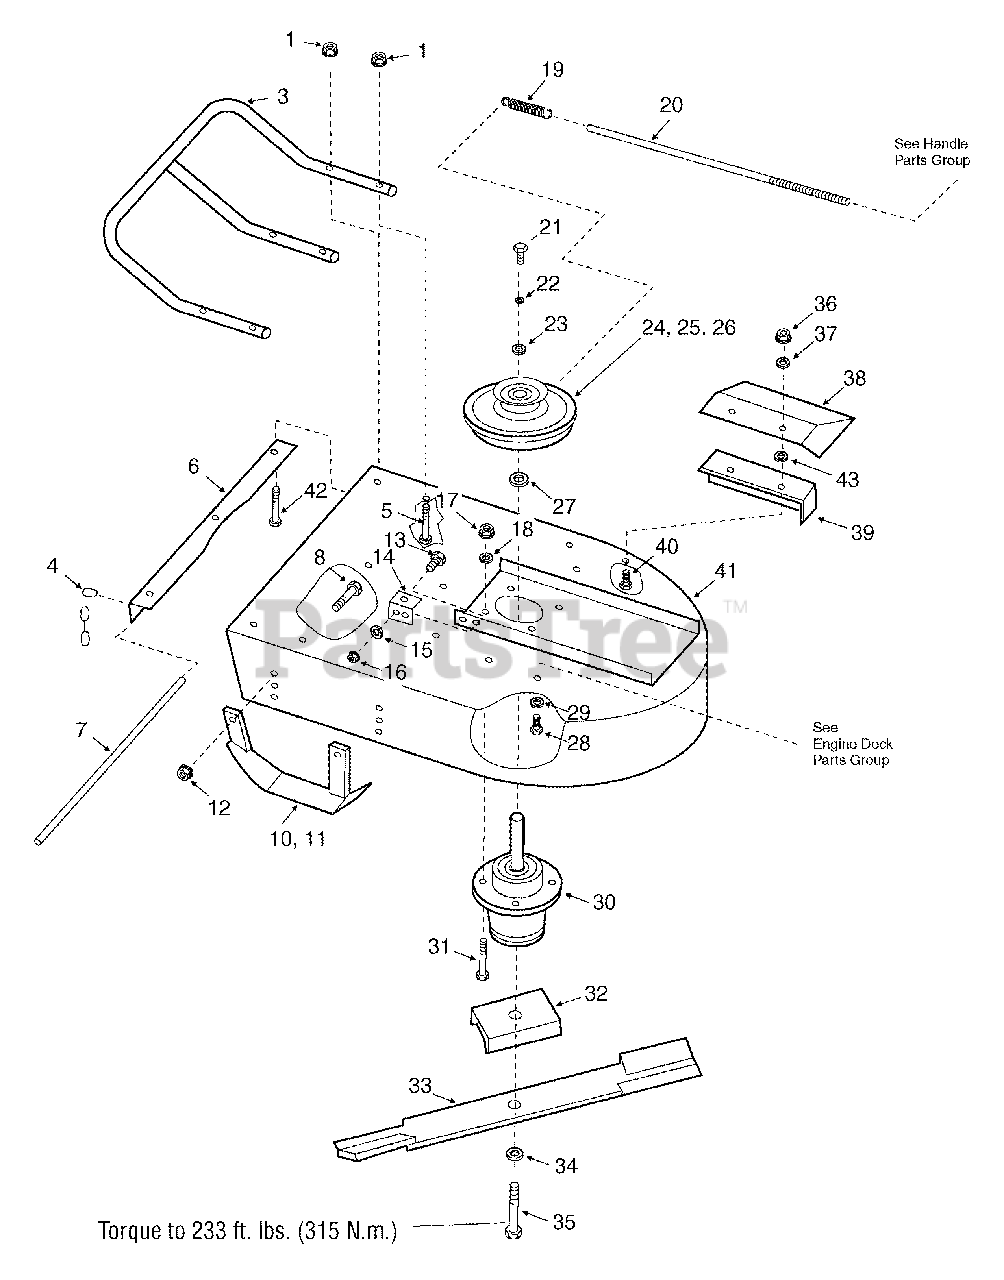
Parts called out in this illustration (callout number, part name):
1	Nut, Hex Flange, 5/16-18
3	Front Bumper Bar
4	Chain Curtain Length
5	Capscrew, Hex Head, 5/16-18 x 1-1/2 (bumper rear holes)
6	Chain Curtain Bracket
7	Chain Curtain Mounting Rod
8	Capscrew, Hex Head, 3/8-16 x 1
10	Blade Deck Skid - Left
12	NU, Hex Flange Whix Lock Sm 3/8-16
13	Capscrew, Hex Head, 5/16-18 x 3/4
14	Anti-torque Bracket
15	Lockwasher, 5/16
16	Nut, Hex, 5/16-18
17	Nut, Hex, 3/8-16
18	Lockwasher, 3/8
19	Clutch Spring
20	Blade Clutch Engagement Rod
21	Capscrew, Hex Head, 3/8-16 x 1-1/2
22	Lockwasher, 3/8
23	Flatwasher, Heavy Duty, 7/16 x 1-1/2
24	Clutch Assembly
27	Clutch Spacer - 1/4
28	Bolt, Hex
29	Washer, 3/8
30	Blade SpindleAssembly
31	Bolt, Hex, 3/8-16 x 1-1/4
32	Cutting Blade Reinforcement Channel
33	Cutting Blade
34	Lockwasher, 5/8
35	Capscrew, Socket Head, 5/8-11 x 1-1/2
36	Nut, Hex, 5/16
37	Lockwasher, 5/16
38	Discharge Deflector
39	Discharge Cover
40	Bolt, Hex, 5/16-18 x 3/4
42	Capscrew, Hex Head, 5/16-18 x 1-3/4 (bumper front holes)
43	Washer, 5/16
